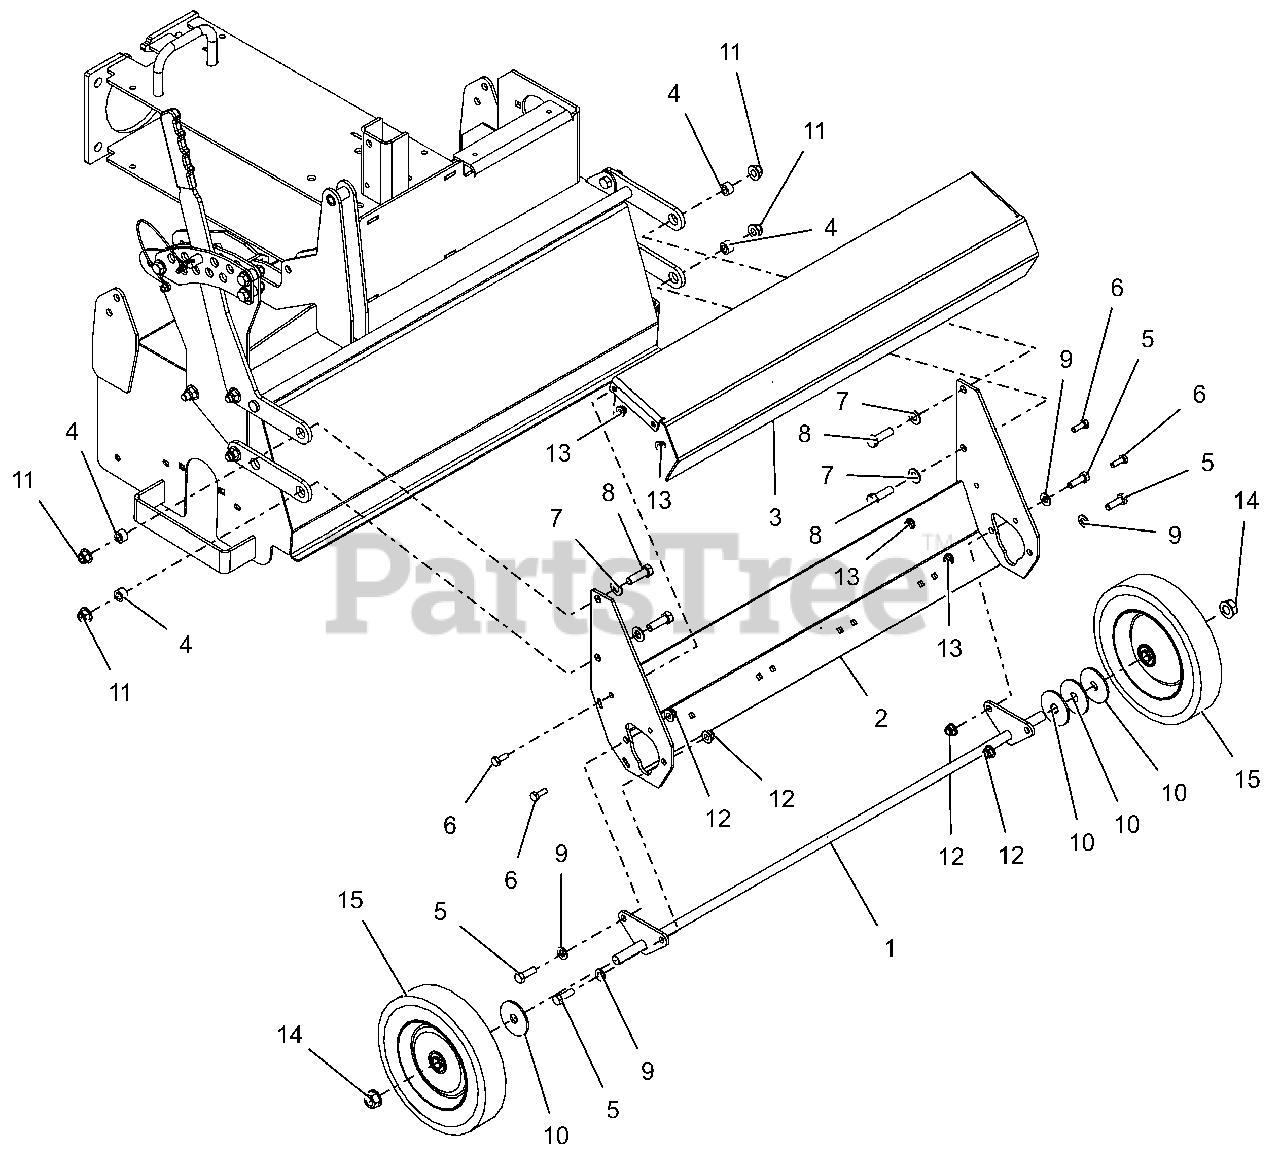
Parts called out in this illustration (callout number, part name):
1	WLDMT, WHEEL MNT (BLACK)
2	WLDMT, WHEEL SUPPORT
3	PLT, COVER FRONT
4	BSHG-SLV .377X.624X.370
5	BLT,HEX .31-18X1.00 G5 ZCC
6	BLT, HEX .25-20X.75 G5 ZCC
7	WSHR,FLT .406X.812X.065 ZCC
8	BLT, HEX .38-16X1.25 G5 ZCC
9	WSHR,FLT .344X.688X.065 ZCC
10	WSHR, FLT .518X2.00X.105 ZCC
11	NUT,NYL-FLG .38-16 GF ZCC
12	NUT,NYL-FLG .31-18 GF ZCC
13	NUT,NYL-FLG .25-20 GF ZCC
14	NUT-LK-CTR-FLG .500-13 GG ZCC
15	WHEEL, 8.0X1.75X.50 - BALL BRG
